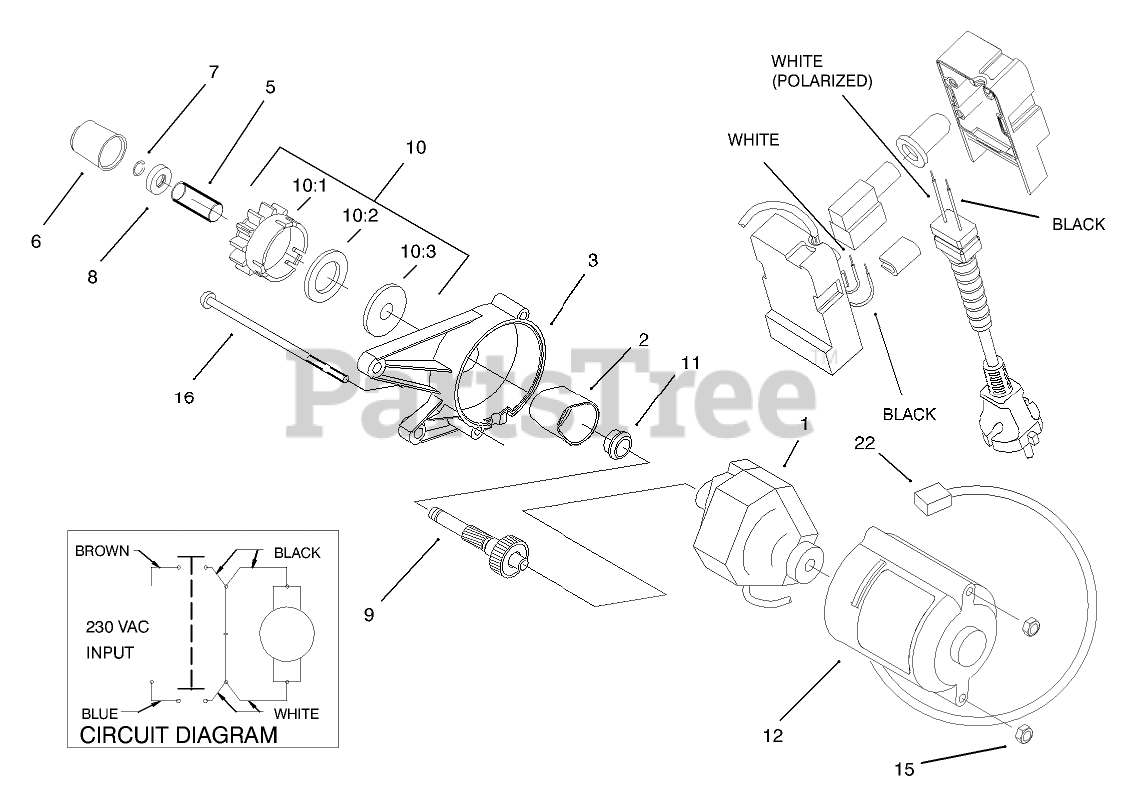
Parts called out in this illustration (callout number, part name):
1	Starter Motor ASM (only on: 38183)
2	Cover-Gear (only on:38183)
3	Housing-UpperStarter (only on:38183)
5	Spring (only on:38183)
6	Pinion-Cap (only on:38183)
7	Ring-Lock (only on:38183)
8	Stop-Pinion (only on:38183)
9	Shaft/GearASM-Service (only on: 38183)
10	Pinion ASM (R & S)(only on: 38183)
10:1	Nut (only on: 38183)
10:2	Pinion (only on:38183)
10:3	Ring-Rubber (only on: 38183)
11	Bushing (only on:38183)
12	Housing-Lower Starter (only on:38183)
15	Nut-Lock Ni (only on:38183)
16	Screw-Mach (only on: 38183)
22	Tie-Cable (only on:38183)
